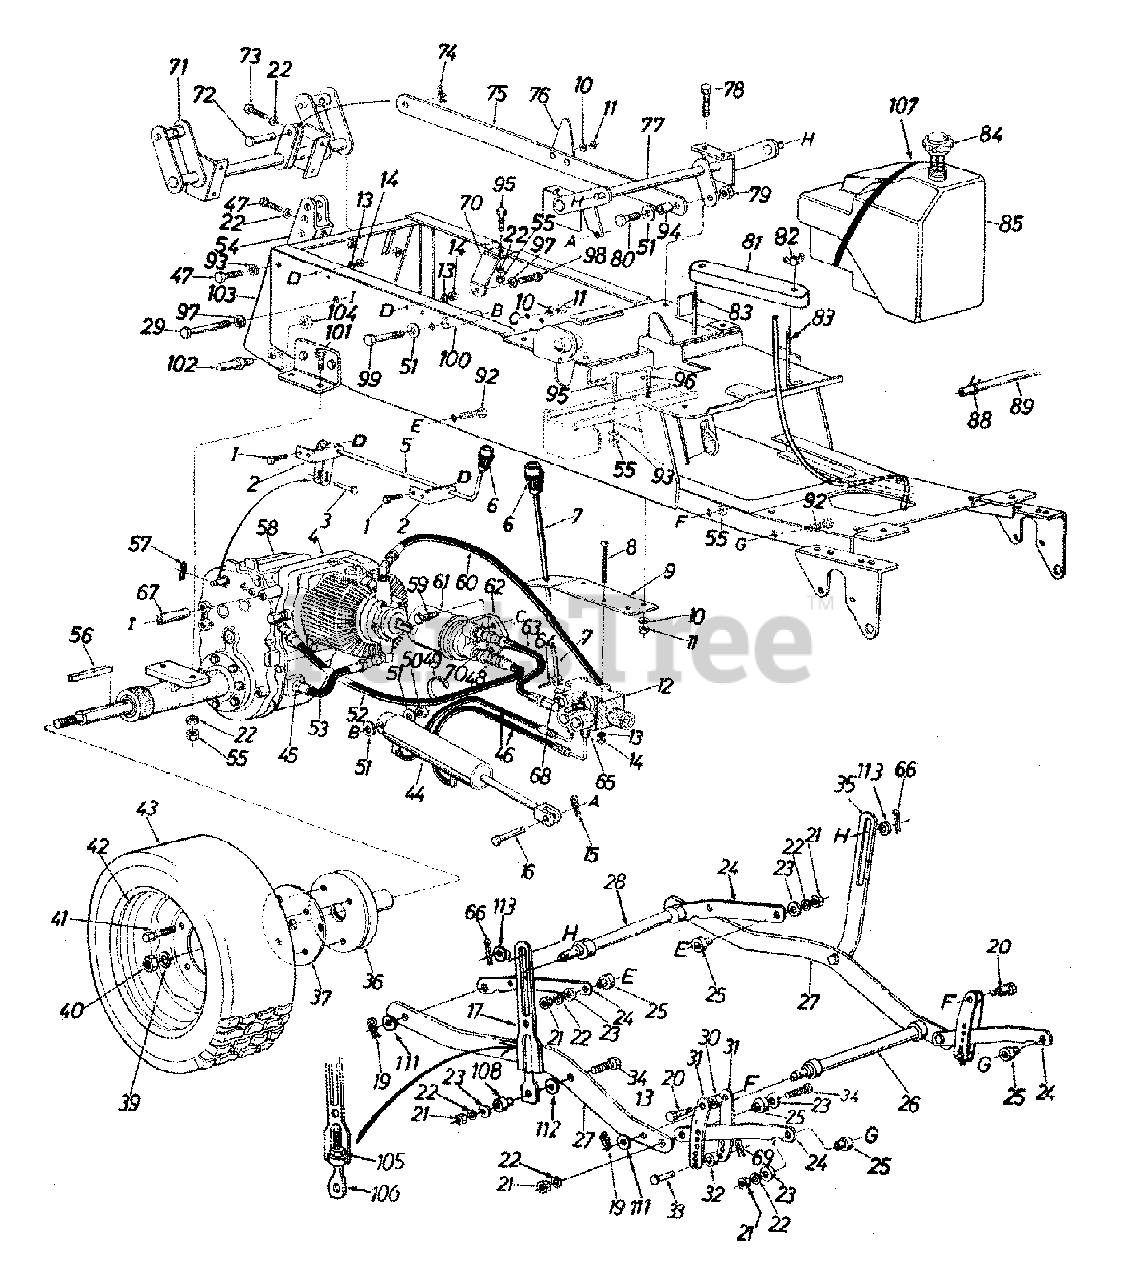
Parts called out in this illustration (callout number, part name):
1	Hex Bolt 1/4-20 x .75" Lg.
2	Hi-Lo Speed Control Brkt.
3	Clevis Pin 1/4" Dia.
4	Hydrostatic Pump Comp.
5	Hi-Lo Control Handle Ass'y.
6	Shift Knob
7	Cylinder Control Handle Ass'y.
8	Truss Mach. Scr. 1/4-20 x 3.00" Lg.
11	Hex Nut 5/16-18 Thd.
12	Valve Ass'y. Comp.
13	L-Wash. 1/4" I.D.
14	Hex Nut 1/4-20 Thd.
15	Hairpin Cotter 1/2" Dia.
16	Clevis Pin 1/2" Dia.
17	Adj. Deck Link
18	Fl-Wash. .62" I.D. x 1.12"
19	Hairpin Cotter
20	Shld. Bolt .498" Dia. x .66"
21	Hex Nut 3/8-24 Thd.
22	L-Wash. 3/8" I.D. - H.D.
23	Fl-Wash. .38" I.D. x 1.00"
24	Lift Arm
25	Shld. Spacer .385" I.D.
26	Cross Shaft Ass'y. - Front
29	Hex Bolt 1/2-13 x 2.75"
30	Collar .50" I.D. x 1.0"
31	Index Brkt.
32	Spacer .38" I.D. x 1.0" O.D.
33	Clevis Pin 3/8" Dia.
34	Hex Bolt 3/8-24 x 1.50" Lg. - Grade 5
39	L-Wash. 3/4" I.D.
40	Hex Ins. L-Nut 3/4-16 Thd.
41	Wheel Lug Bolt
42	Rear Wheel Rim Only
44	Hydraulic Cylinder
45	7/8-14 UNF-2A Thd. 5/8 Tube Fitting
46	Valve to Cylinder Hose - 20"
47	Hex Bolt 3/8-16 x .75" Lg. - Grade 5
48	Bushing Reducer 1/2-14 NPTF to 3/8-18 NPTF
49	Cable Tie
50	Hex Jam Nut 1/2-20 Thd.
51	Fl-Wash. .50" I.D. x 1.25
52	Filter Return Hose 24" Lg.
53	Pump Tube Ass'y.
54	Hitch Brkt.
55	Hex Nut 3/8-16 Thd.
56	Sq. Key 1/4" x 1/4" x 2"
57	Hairpin Cotter 1/4" Dia.
58	Peerless Transaxle
59	Hex Bolt 5/16-18 x 1.25"
60	Pump to Valve Hose
61	Fram Filter Ass'y. PH-16
62	Filter Base
63	Valve to Filter Hose - 8.38"
64	Spring Pin Spiral 1/8" Dia.
65	Flare Adapter
66	Cotter Pin 1/8" Dia. x 1.0"
67	Spacer
68	Adapter 9/16-18 to 9/16-18
69	Hairpin Cotter
70	Transmission Brace
71	Rear Lift Shaft Ass'y.
72	Clevis Pin
73	Hex Scr. 3/8-16 x 1.00" Lg. Grade 5
74	Cotter Pin 1/8" Dia. x 1.25"
75	Push Bar Ass'y.
76	Position Indicator
79	Hex Cent. L-Nut 1/2-20 Thd.
80	Hex Scr. 1/2-20 x 1.25" Lg.
81	Battery Cover
82	Wing Nut 1/4-20 Thd.
83	Battery Hold Down Rods
84	Gas Tank Cap
85	Gas Tank Ass'y.
88	Gas Line Clamp 1/2"
89	Gas Line 20" Lg.
92	Hex Scr. 3/8-24 x 1.50" Lg.
93	L-Wash. 3/8" Scr.
94	Push Bar Sleeve
95	Hex Scr. 3/8-16 x 1.00" Lg. - Grade 5
96	Hex Scr. 5/16-18 x .75" Lg.
97	L-Wash. 1/2" Scr.
98	Hex Scr. 1/2-13 x 1.25" Lg.
99	Hex Scr. 1/2-20 x 3-1/2" Lg. - Grade 5
100	Spacer for Cylinder
101	Hex Scr. 3/8-16 x 1.75" Lg.
102	Link Clevis Pin
103	Hitch Plate Ass'y.
104	Hex Cent. L-Nut 5/8-18 Thd.
105	Hex Nut 1/2-13 Thd.
106	Eye Bolt
107	Tie Strap
108	Spacer .385" I.D.
109	Dipstick Tube Ass'y.
110	Dipstick Ass'y.
111	Fl-Wash. .63" I.D. x .93" O.D.
112	Fl-Wash. .381" I.D. x .87" O.D.
113	Fl-Wash. .5" I.D. x 1" O.D.
